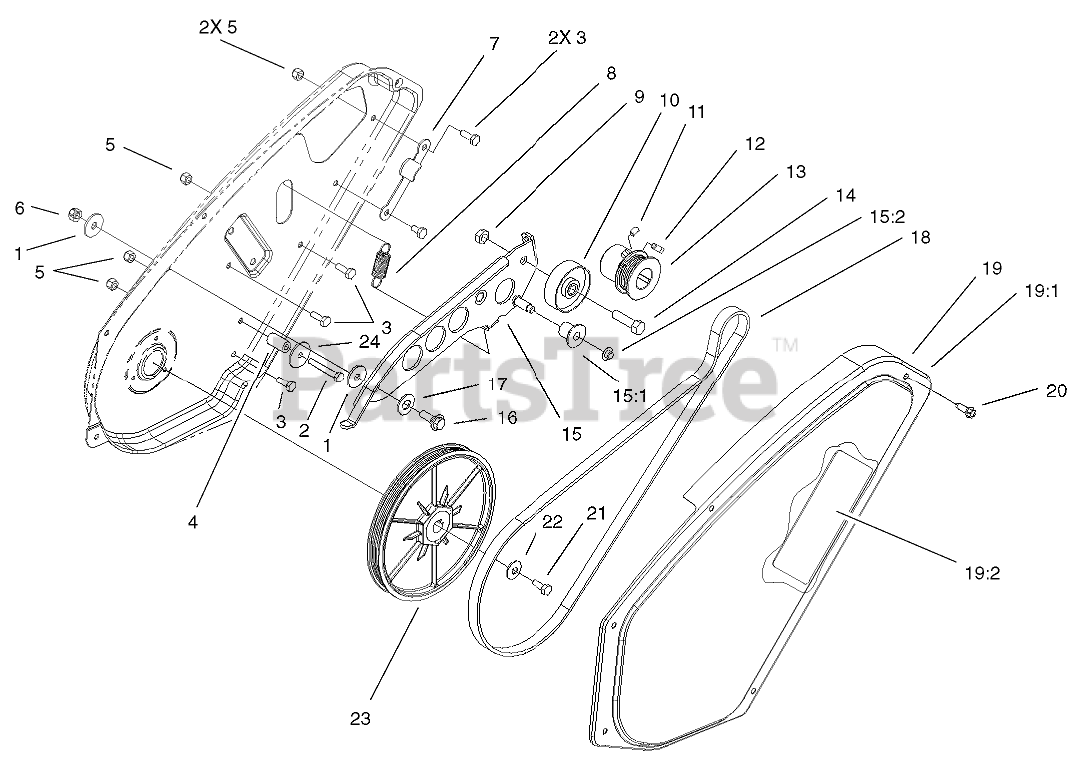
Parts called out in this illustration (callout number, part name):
1	WASHER-PIVOT
2	SCREW-HH
3	SCREW-HH
4	SLEEVE-GUIDE, BELT
5	NUT-LOCK, NI
6	NUT-LOCK, NI
7	BELT-GUIDE
8	SPRING
9	NUT-LOCK, CONE
10	PULLEY-IDLER
11	SCREW-HSH
12	SCREW-SQH
13	PULLEY
14	SCREW-HH
15	BRAKE-ARM
15:1	ROLLER-BRAKE
15:2	NUT-PUSH
16	SCREW-SHOULDER
17	WASHER
18	BELT-DRIVE
19	Cover-Drive W/Decal (only on: 38600, 38602)
19	Cover-Drive W/Decal Ce (only on: 38601, 38603)
19:1	Decal-Hot Surface (only on: 38600, 38602)
19:1	Decal-Hot (only on: 38601, 38603)
19:2	DECAL-ROUTING, BELT
20	SCREW-HWHTF
21	SCREW-HH
22	WASHER-BELLEVILLE
23	PULLEY-ROTOR
24	WASHER-FLAT
